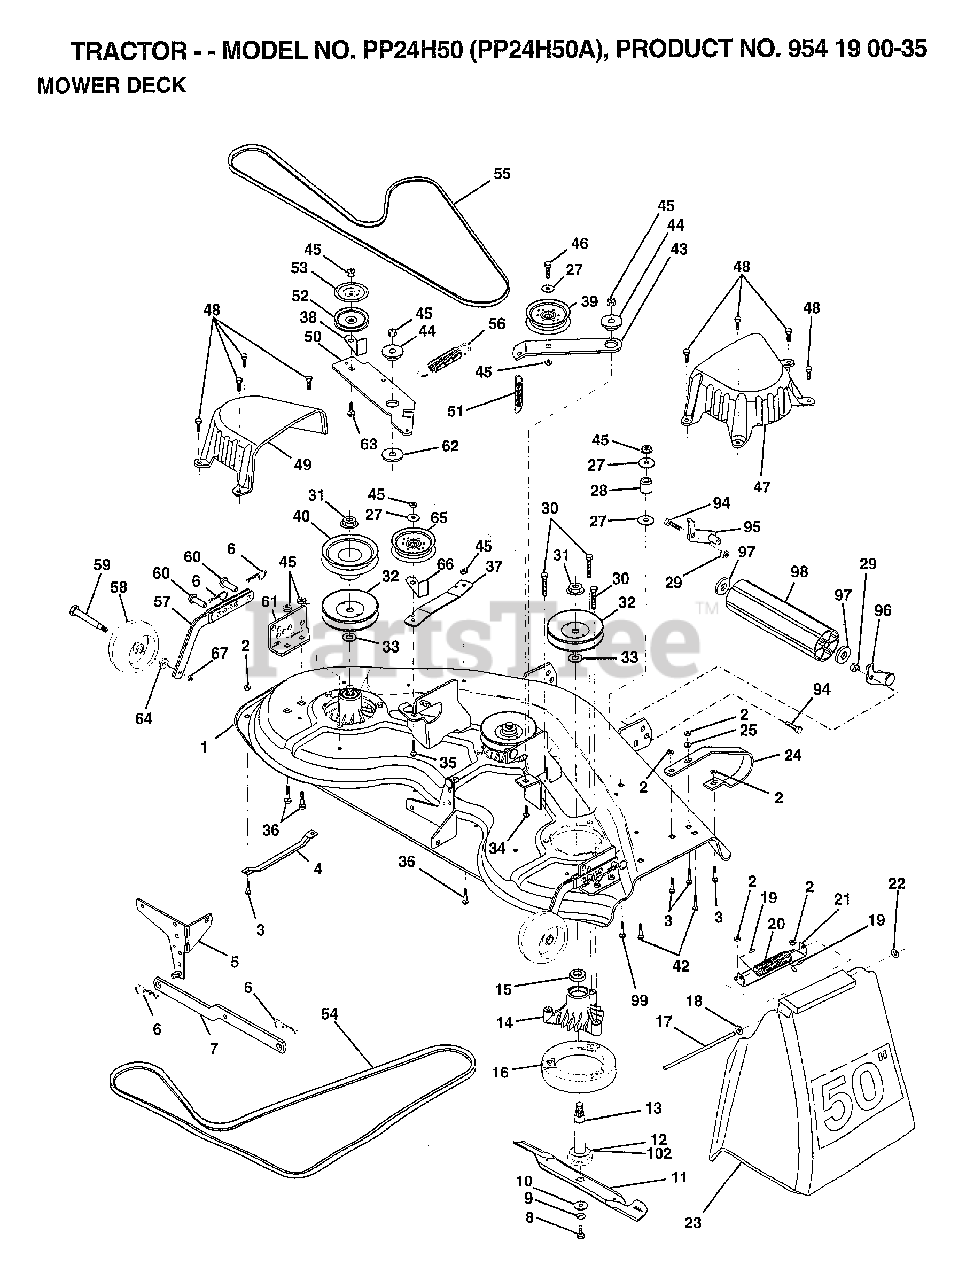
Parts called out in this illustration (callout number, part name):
1	"DECK ASM-50"""
4	RUNNER-LH M
5	BRKT.ASM.SW.44/50
8	BLADE BOLT
10	WASHER.HARD.BLADE
11	"BLADE.50"" HD"
12	BEARING.BALL
13	SHAFT.ASM.W/BRNG
14	HOUSING.MAND.44.V
15	BEARING
16	STRIPPER RND MWR
17	ROD-HINGE T
18	WASHER
19	CAP-SLEEVE LT
20	SPRING TORSION
21	BRKT DEFLECTOR
22	NUT PUSH M
23	DEFLECTOR
24	"RUNNER RH 50"" DK"
25	WASHER M
27	WASHER
29	NUT
30	"SCREW-THD ROLL,WA"
32	PULLEY.MANDREL.42
33	WASHER
34	BOLT.3/8-14X1.25
35	BOLT
36	BOLT D
37	STIFFENER.ARM.IDL
38	"KEEPER-BELT,IDLER"
39	FLAT IDLER PULLEY
40	"PULLEY.DRIVEN.44"""
42	BOLT
43	"ARM.IDLER.SEC.44"""
44	SPACER RETAINER
47	"COVER.MAND.RH.44"""
48	SCREW.1/4-20X5/8
49	COVER.MANDREL.LH
50	ARM.IDLER.PRIMARY
51	"SPRING.SEC.44""VEN"
52	PULLEY.IDLER.VGRO
53	SHIELD.IDLER.44.V
54	BELT V PRIM 50
55	BELT-V.SEC.46.KEL
56	SPRING.EXT.DECK.
57	BAR.ASM.GUAGE.WHL
58	WHEEL GAGE DONUT
59	BOLT.SHOULDER
60	PIN.CLEVIS
61	BRACKET.GUAGE.WHL
62	HARDENED WASHER
63	BOLT.3/8-16X1.50
64	WASHER
65	PULLEY IDELR FLAT
66	"KEEPER-BELT,IDLER"
67	LOCKNUT
94	BOLT
97	WASHER
99	BOLT
102	WASHER.FELT.
